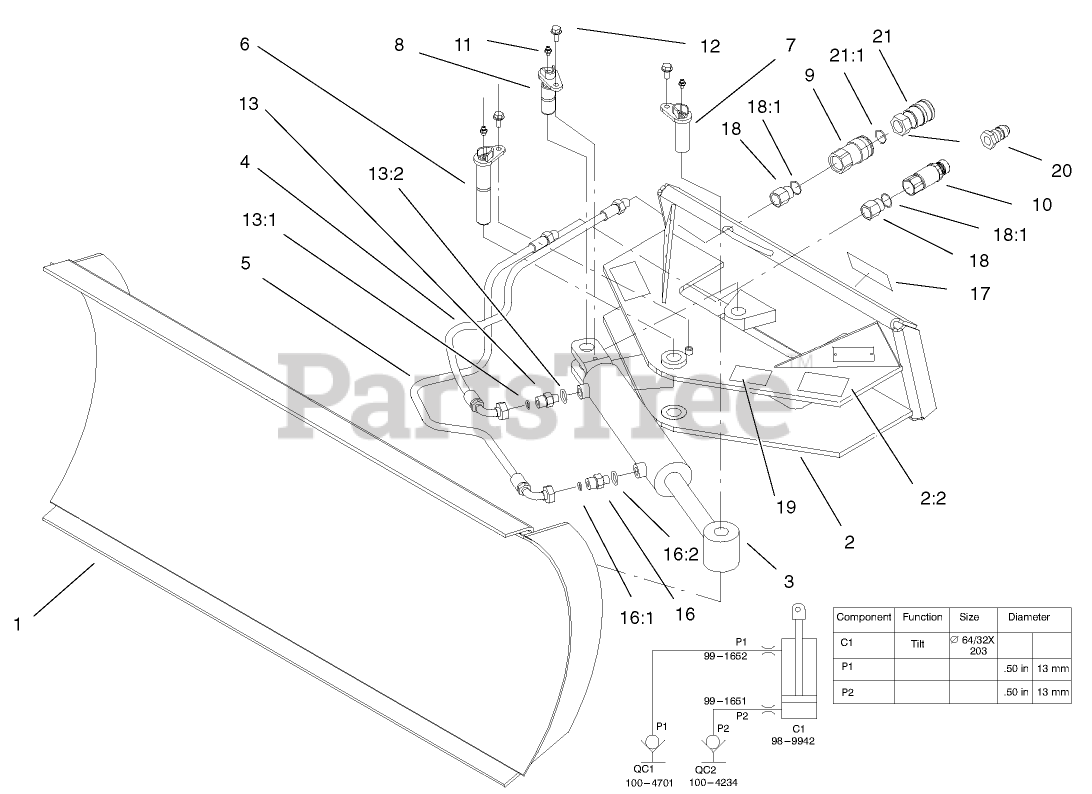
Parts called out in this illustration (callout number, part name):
1	BLADE ASM
2	BLADE PIVOT ASM
2:2	DECAL-WARNING
3	CYLINDER-HYD
4	HYD HOSE ASM
5	HYD HOSE ASM
6	PIN-PIVOT
7	PIN-PIVOT
10	NIPPLE-CONNECT, PRESSURE
11	FITTING-GREASE
12	SCREW-HWHTF
13	FITTING-STRAIGHT
13:1	O-RING
13:2	O-RING
16	FITTING-STR,ORIF
16:1	O-RING
16:2	O-RING
18	ADAPTER-HYD
18:1	O-RING
19	DECAL
20	DISCONNECT-QUICK, MALE
21	DISCONNECT-QUICK, FEMALE
